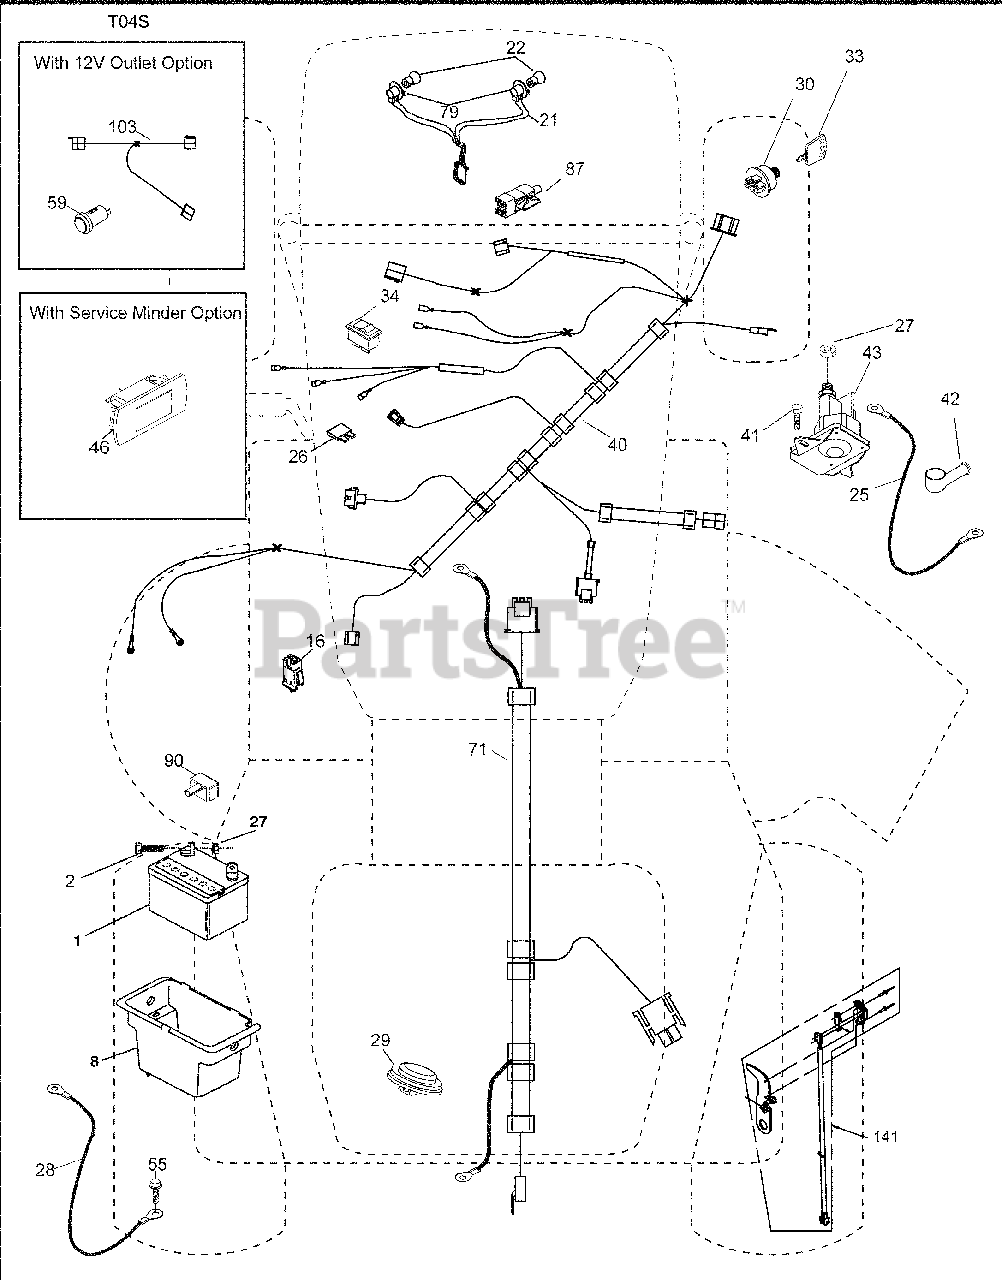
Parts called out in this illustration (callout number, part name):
1	Battery
2	Bolt Hex Head 1/4-20 x 3/4
8	Box Battery
16	Switch Interlock Push-In
21	Harness Socket Light w/4152J
22	Bulb Light
25	Cable Starter
27	Nut Keps Hex 1/4-20 unc
28	Cable, Ground
29	Switch, Seat
30	Switch, Ign
33	Key/Chain
34	Switch Light/Reset
40	Harness Ign. Dash
41	Screw Thd Cut 1/4-20 x 1/2
42	Cover, Terminal
43	Solenoid
46	Gauge Servicereminder Hrmtr
55	Screw Thdrol 5/16-18 x 3/4 TYTT
71	Harness Ign.
79	Socket Asm. Bulb
87	Switch Interlock
90	Cover Terminal
141	Kit T2 ROS
